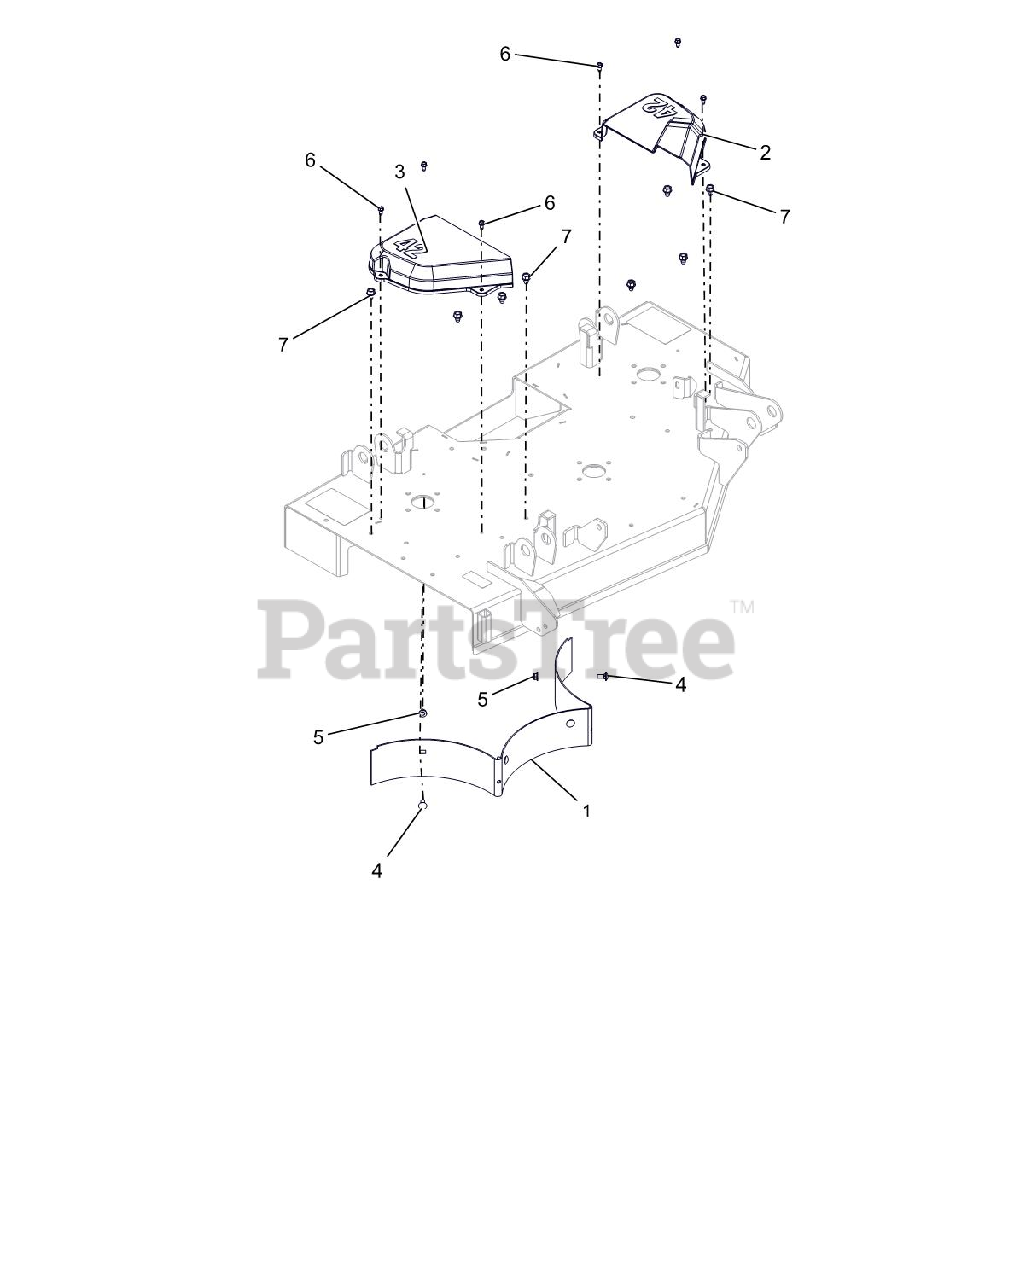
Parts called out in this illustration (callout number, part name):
1	BAFFLE, REAR 42
2	COVER, BELT 42" LH
3	COVER, BELT 42" RH
4	@BLT-RDHDSQNK .31-18X.75 G5YZ
5	@NUT-LK-TOP-FLG .31-18 YWZC
6	SCR-TAP .25-20X.50 HWH TR YWZ
7	@SCR-TAP .38-16X.50 HWH TR YWZ
